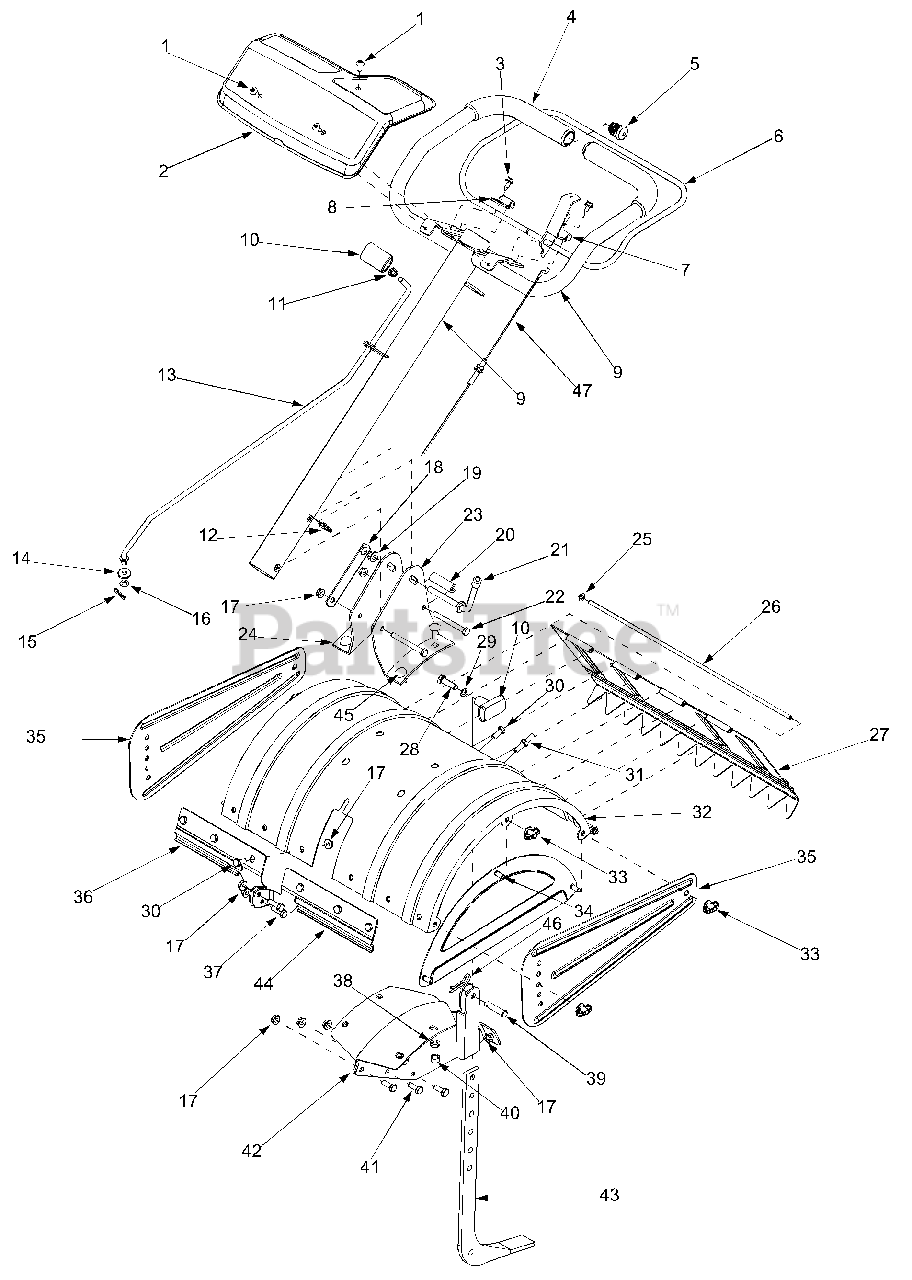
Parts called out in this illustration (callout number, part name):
1	Tap Screw 1/4-14 x.625
4	Foam Grip
5	End Plug
11	Jam Nut 3/8-16
12	Cable Clip
13	Shift Control
14	Rubber Washer.33 ID x.87 OD
15	Cotter Pin
16	Flat Washer.344 ID x.62 OD
17	Hex Flange Lock Nut 5/16-18
18	Retainer Bracket
19	Flange Lock Nut 3/8-24
20	Spacer.322 ID x.625 OD
21	Adjustable Crank Handle
22	Hex Screw 5/16-18 x 3.0
28	Hex Cap Screw 3/8-16 x 1.25
29	Flat Washer.375 ID x.620 OD
30	Hex Cap Screw 5/16-18 x.75
31	Hex Screw 5/16-18 x.75
38	Lock Washer 3/8
39	Clevis Pin
40	Hex Nut 3/8-16
41	Hex Cap Screw 5/16-18 x.875
46	Cotter Pin
47	Clutch Cable
